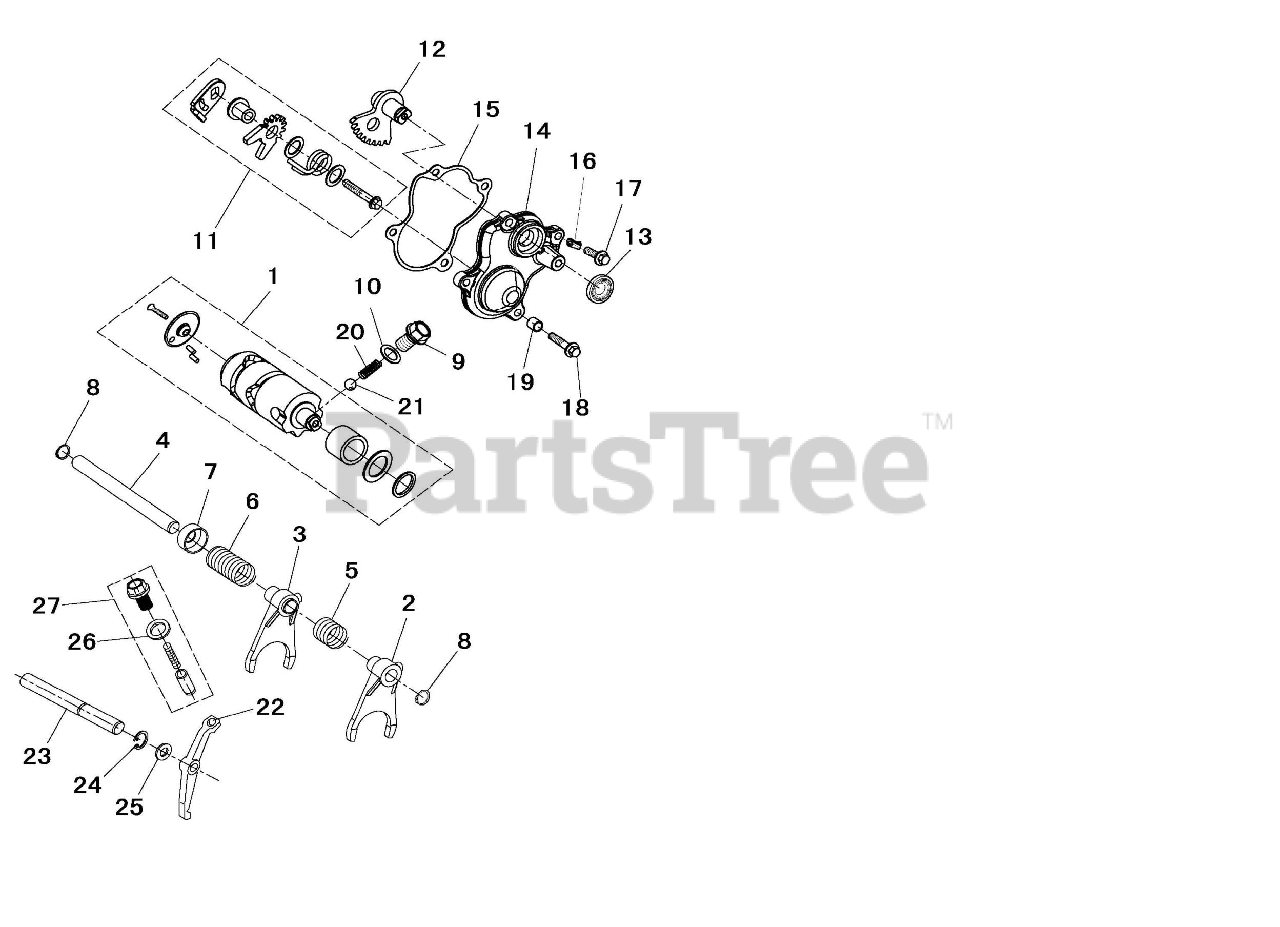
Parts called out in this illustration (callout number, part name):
1	SHIFT DRUM
2	Shifting Fork ?
3	Shifting Fork ?
4	Shift Rail
5	Spring, R gear
6	Spring,HL gear
7	Spring seat,Shift Rail
8	Circlip for shaft ?12
9	Hollow Bolts M14X1.5X21
10	Copper Washer 14X21X1
11	Shift Dialing Plate Assy
12	Shiftshaft Assy
13	Oil Seal 15X25X5
14	Shiftshaft Cover
15	Gasket,Shiftshaft Cover
16	CLAMP
17	Hex flange bolts M6X20
18	Hex flange bolts M6X30
19	Pin,Dowel 8X12
20	Spring 24X1
21	Steel Ball 9.5
22	PARKING ARM
23	PARKING ARM SHAFT
24	Circlip for shaft ?12
25	WASHER 12.3 X 20 X 1
26	Copper Washer 14?21?2
27	PARKING BOLT ASSEMBLY
